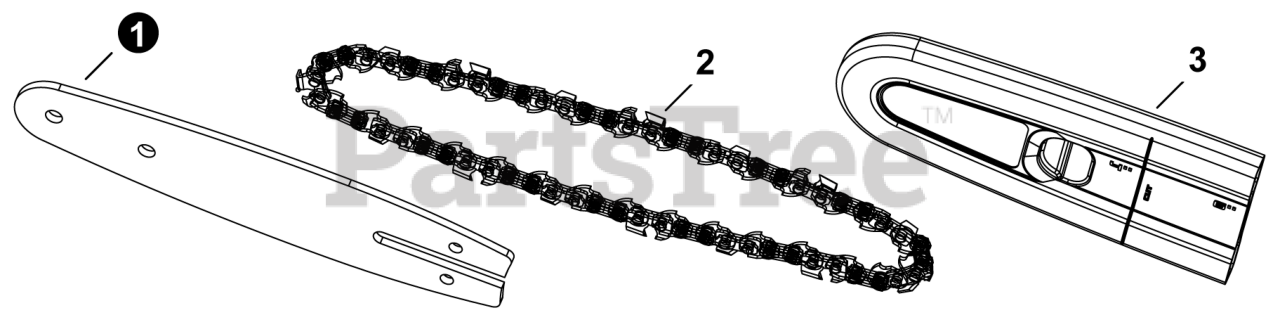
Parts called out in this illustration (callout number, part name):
1	GUIDE BAR
2	SAW CHAIN
3	SCABBARD
